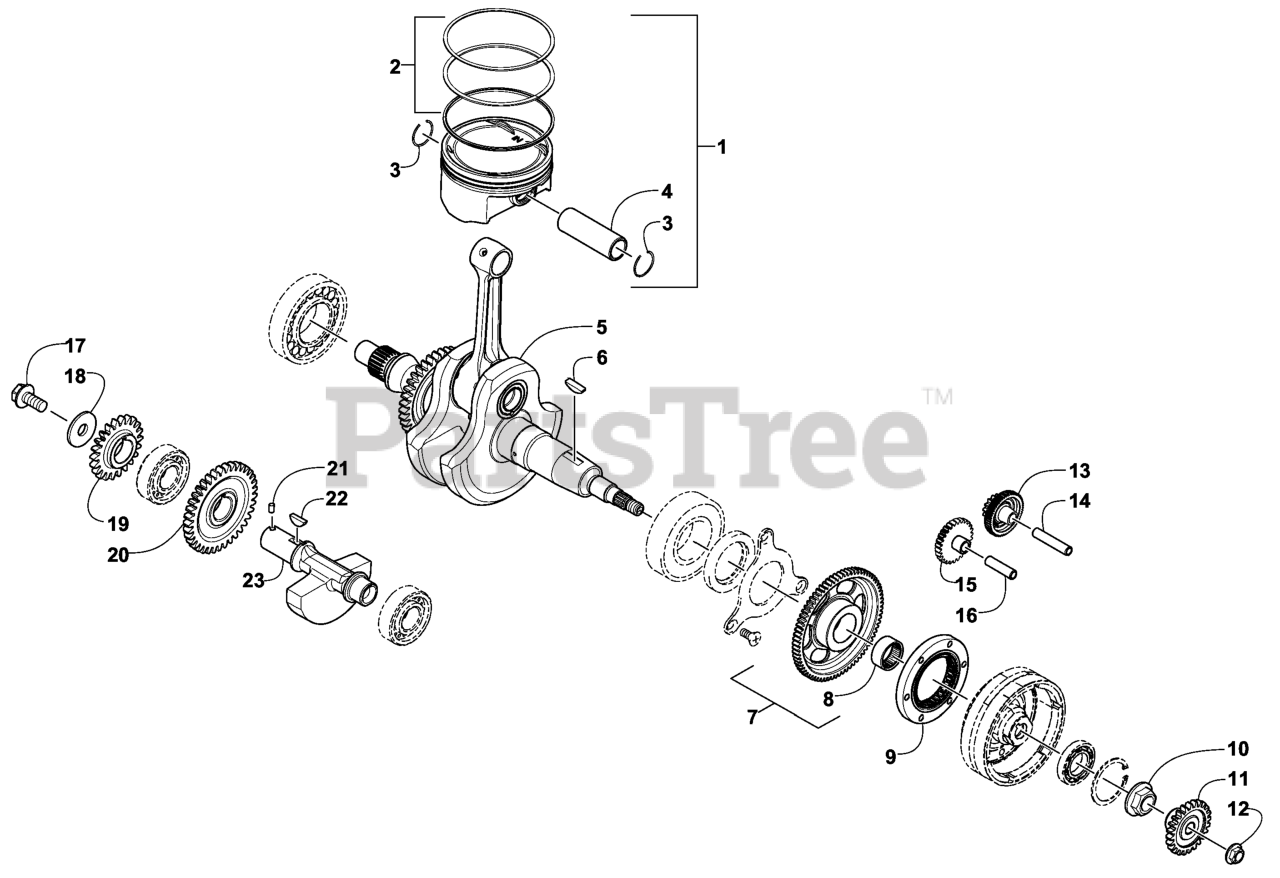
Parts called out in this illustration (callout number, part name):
1	PISTON SET
2	PISTON RING SET
3	CIRCLIP-PISTON PIN
5	CRANKSHAFT ASM
7	GEAR-STARTER CLUTCH, 73T
8	BEARING-NEEDLE, ROLLER
9	CLUTCH-ONE WAY (W/ HUB AS
10	NUT-HHF
11	GEAR-DRIVEN, PRIMARY
12	NUT-HHF
13	GEAR-STARTER IDLER, 56/14
14	PIN-STARTER IDLER, GEAR N
15	GEAR-STARTER IDLER, 27T (
16	PIN-STARTER IDLER, GEAR N
17	SCREW-HFH
18	WASHER-STEEL
20	GEAR-DRIVEN, NO. 1
21	PIN-DOWEL
22	KEY-WOODRUFF
23	SHAFT-BALANCER
